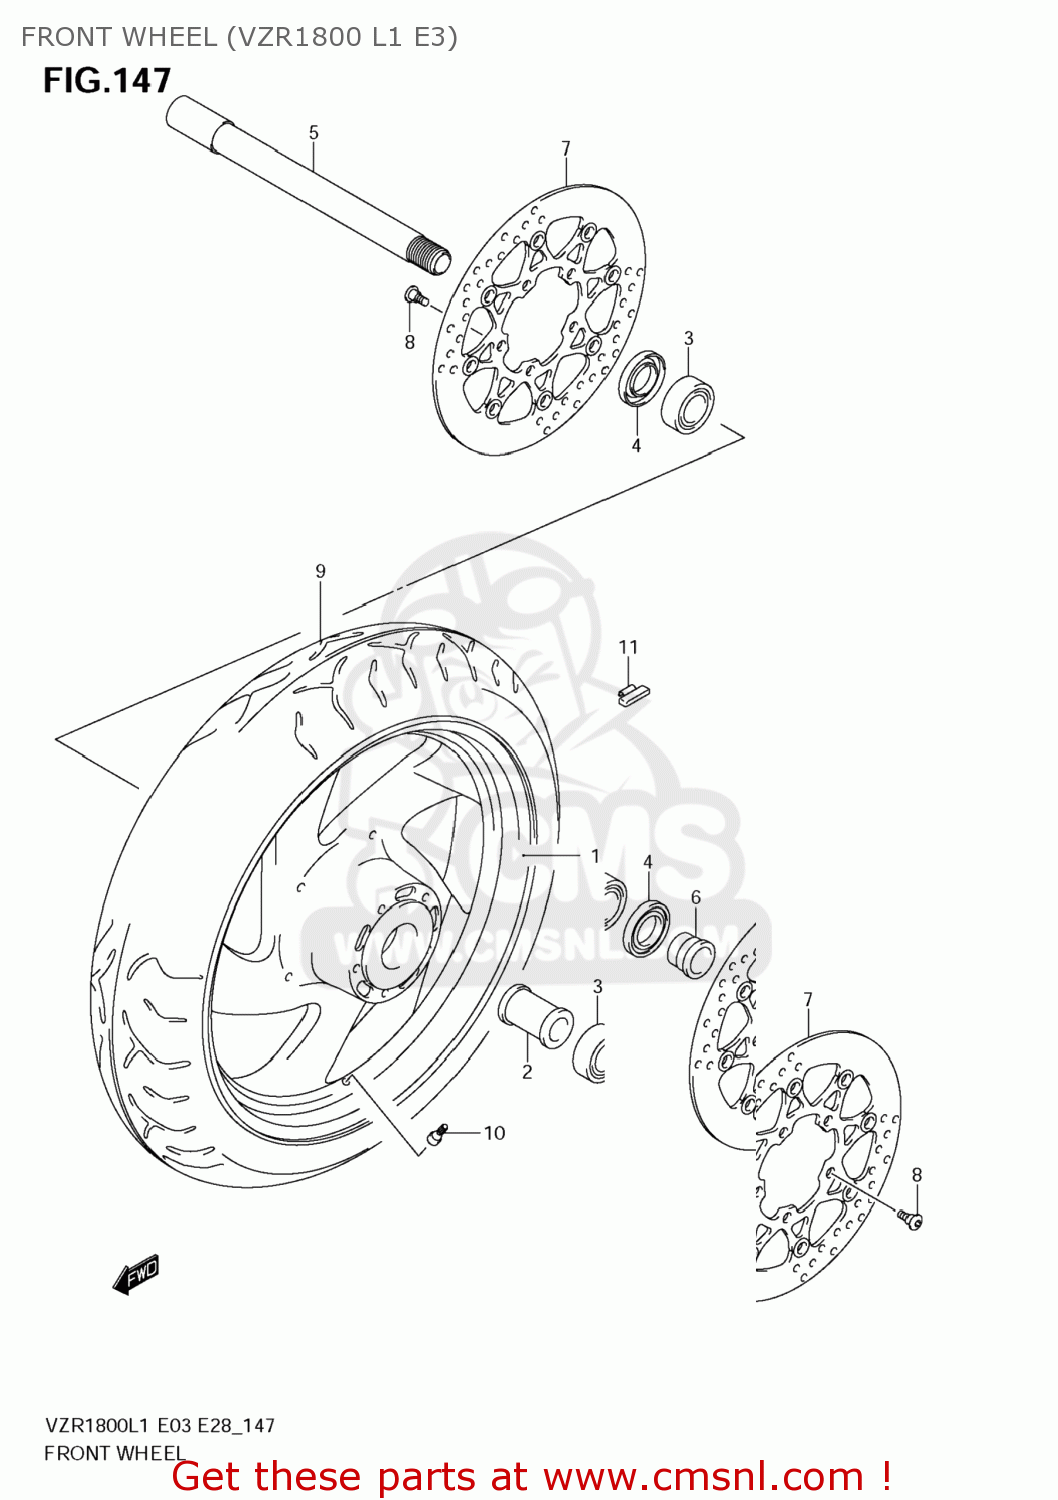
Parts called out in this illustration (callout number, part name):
1	WHEEL,FR(18M/CXMT3.50)
2	SPACER,FR WHEEL BEARING
3	BEARING(25X52X15)
4	SEAL,OIL(32X52X7)
5	AXLE,FR
6	SPACER,FR AXLE,L
7	DISC,FR BRAKE
8	BOLT(8X21)
9	TIRE,FR,130/70
10	VALVE ASSY,WHEEL RIM(TR412)
11	BALANCER,WHEEL(10G)
